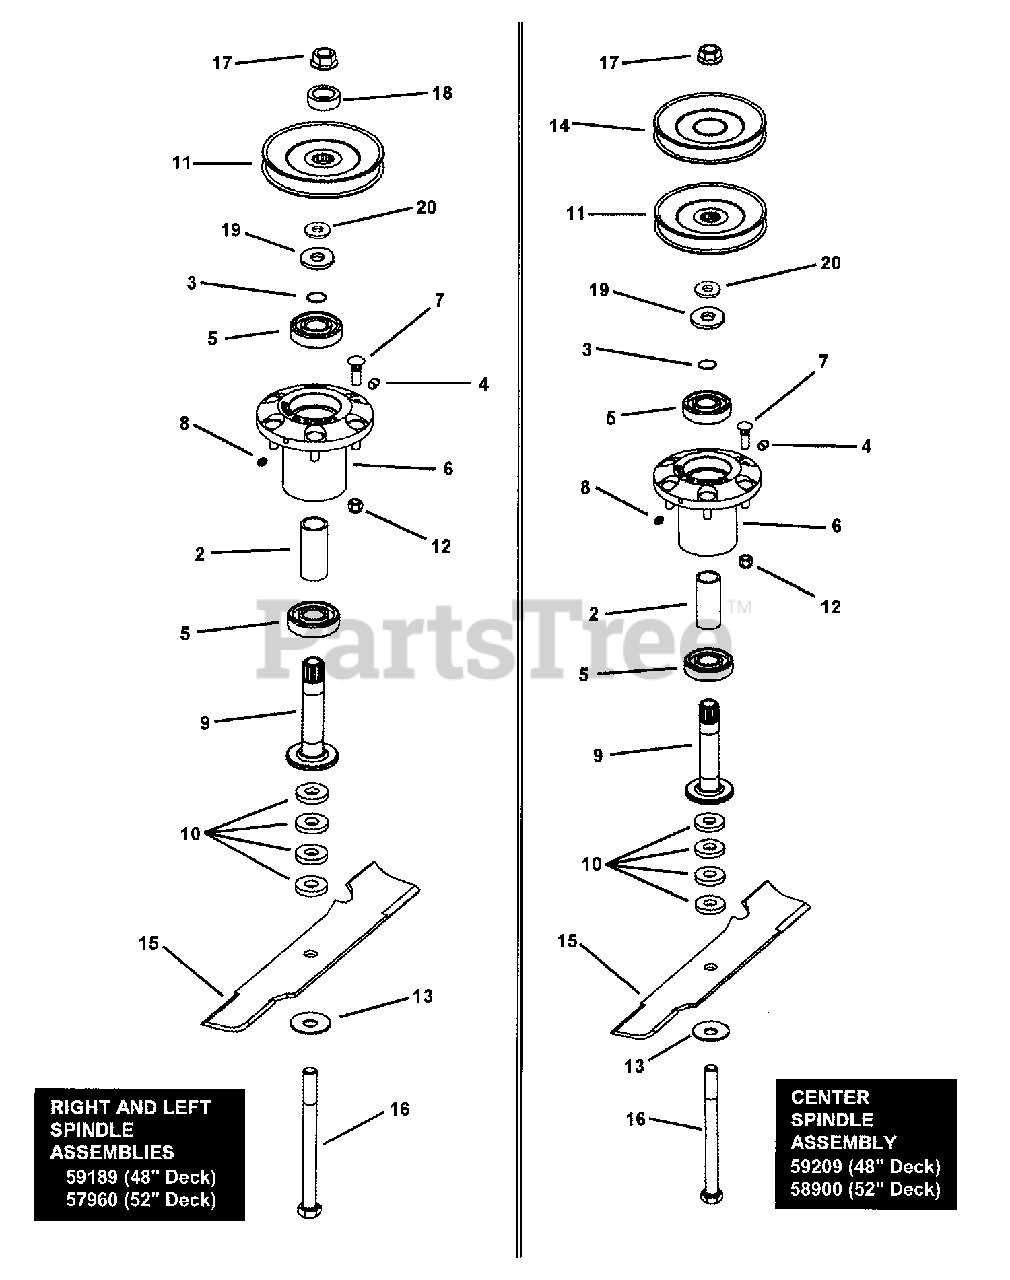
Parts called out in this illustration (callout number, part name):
1	SUB-ASSEMBLY, Spindle (Incl. the 8 items below)
2	SPACER, Bearing
3	RING, Spindle Retaining
4	VENT, Spindle (Alemite # 321839)
5	BALL BEARING (2 per item 1, sub-assembly)
6	HOUSING, Spindle
7	BOLT, Ribbed (3/8-16 x 1-1/4" Thread)
8	FITTING, Lube (1/4-28 Thread; Lincoln # 5042)
9	ASSEMBLY, Spindle Shaft
10	SPACER, Blade
11	PULLEY, 5-3/4" Diameter
12	NUT, 3/8-16 HEX NYLON LOCK (6 per spindle assembly)
13	WASHER, Beveled
14	PULLEY, Driven (48" Deck only)
15	BLADE, 16-1/2" (48" Deck only)
16	BOLT, 5/8-11 x 7-1/2" Hex, Grade 5
17	NUT, 5/8-11 Hex Flange Lock, GR 5
18	WASHER, Spindle
19	SEAL, Nylos
20	WASHER
